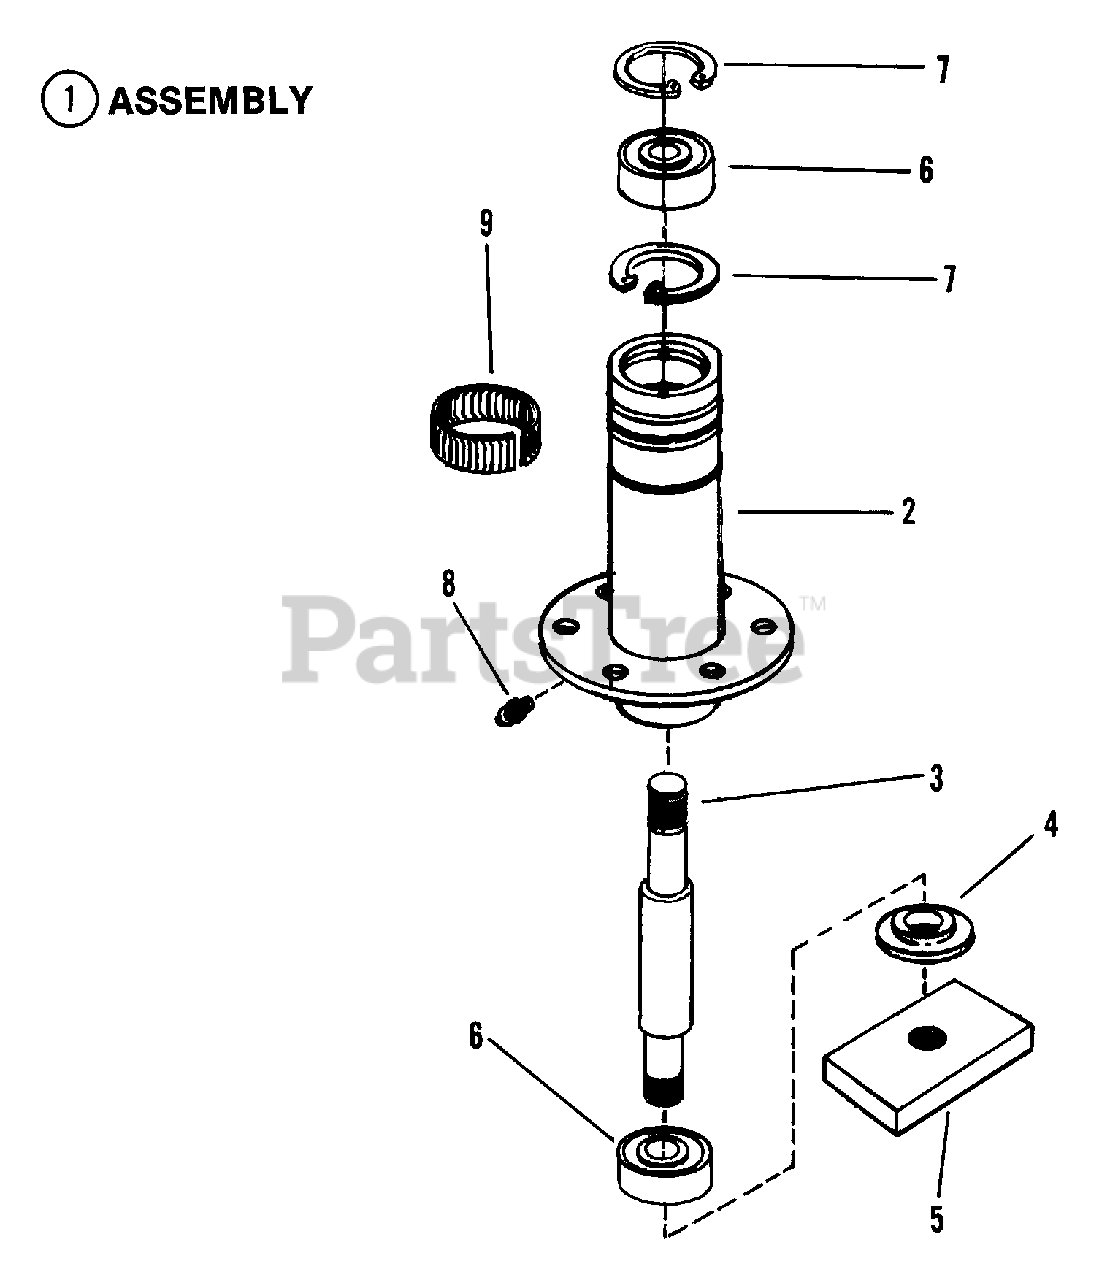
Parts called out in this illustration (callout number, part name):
1	ASSEMBLY, Spindle
2	HOUSING, Spindle
3	SPINDLE (9.5" Long)
4	WASHER, Spindle
5	HOLDER,Blade
6	BEARING
7	RING, Retaining
8	FITTING, Lube (Press fit for .187 hole-no ball)
9	RING, Tolerance
